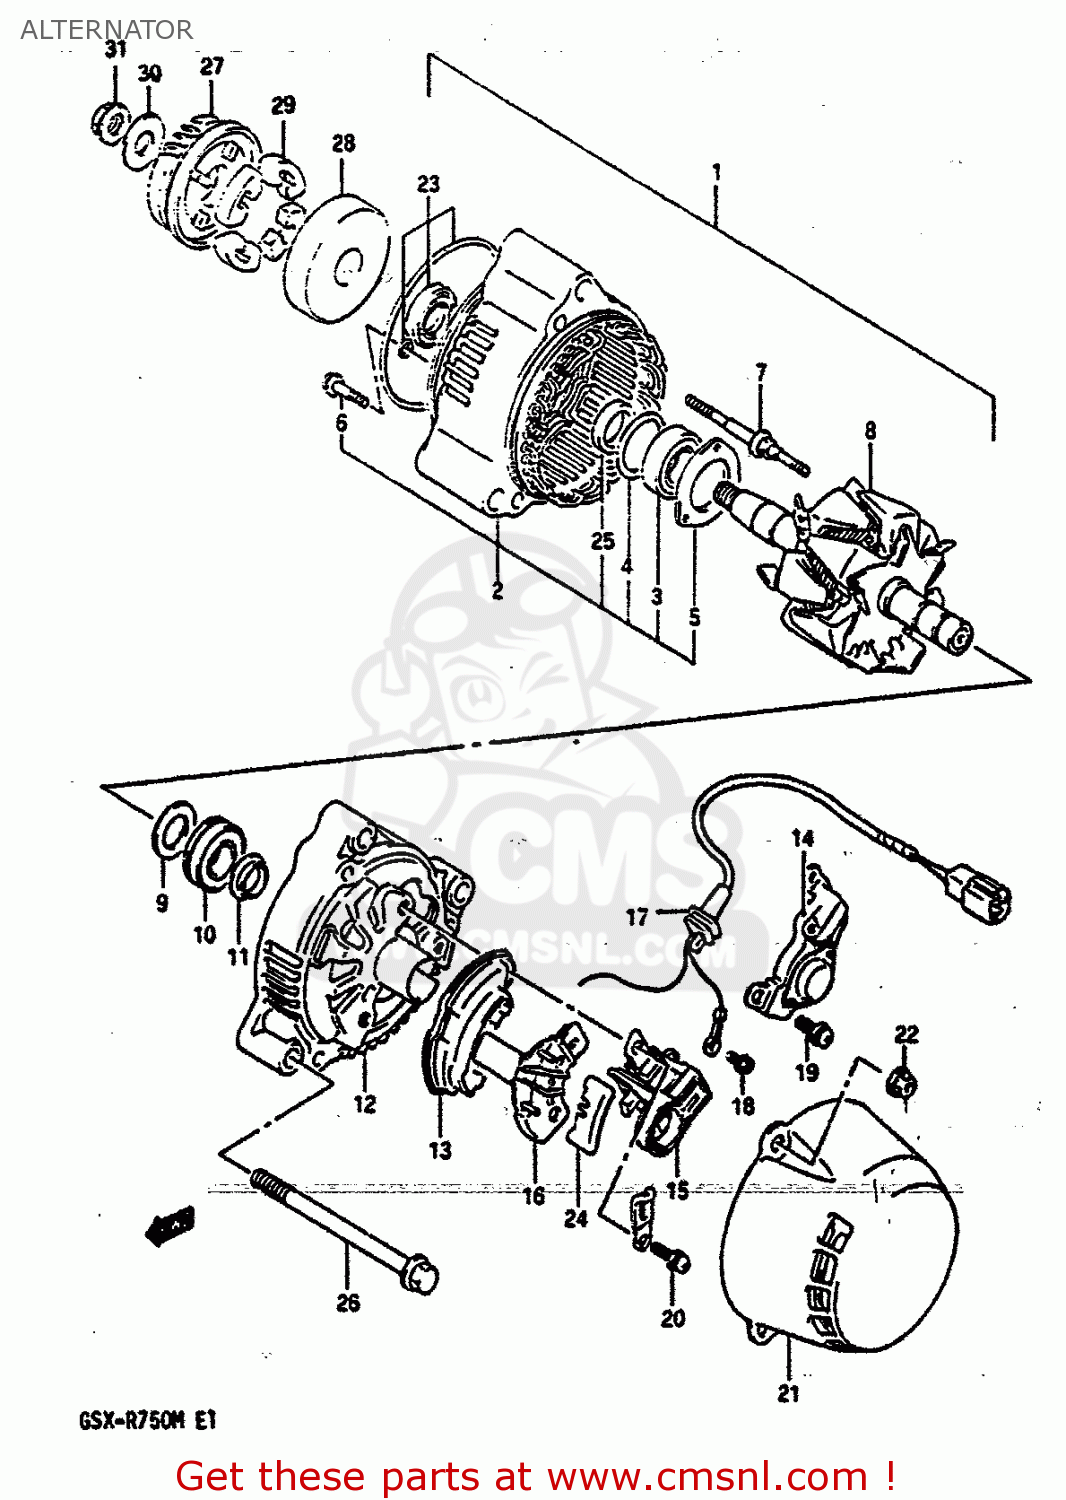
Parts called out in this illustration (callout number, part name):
1	GENERATOR ASSEMBLY
2	FRAME,DRIVE END
3	BEARING
4	COVER,BEARING
5	RETAINER
6	SCREW,BEARING RETAINER
7	STUD BOLT
8	ROTOR ASSEMBLY
9	COVER,BEARING
10	BEARING
11	COVER(2)
12	FRAME,END
13	HOLDER,RECTIFIER
14	REGULATOR
15	HOLDER,BRUSH
16	COVER,RECTIFIER
17	WIRE,LEAD
18	SCREW
19	SCREW
20	SCREW
21	COVER
22	NUT ,5MM
23	SEAL SET,OIL
24	BUSH
25	SPACER
26	BOLT 8X90
27	GEAR,GENERATOR DRIVEN
28	HOUSING,GENERATOR GEAR
29	DAMPER,GENERATOR DRIVEN
30	WASHER
31	NUT
